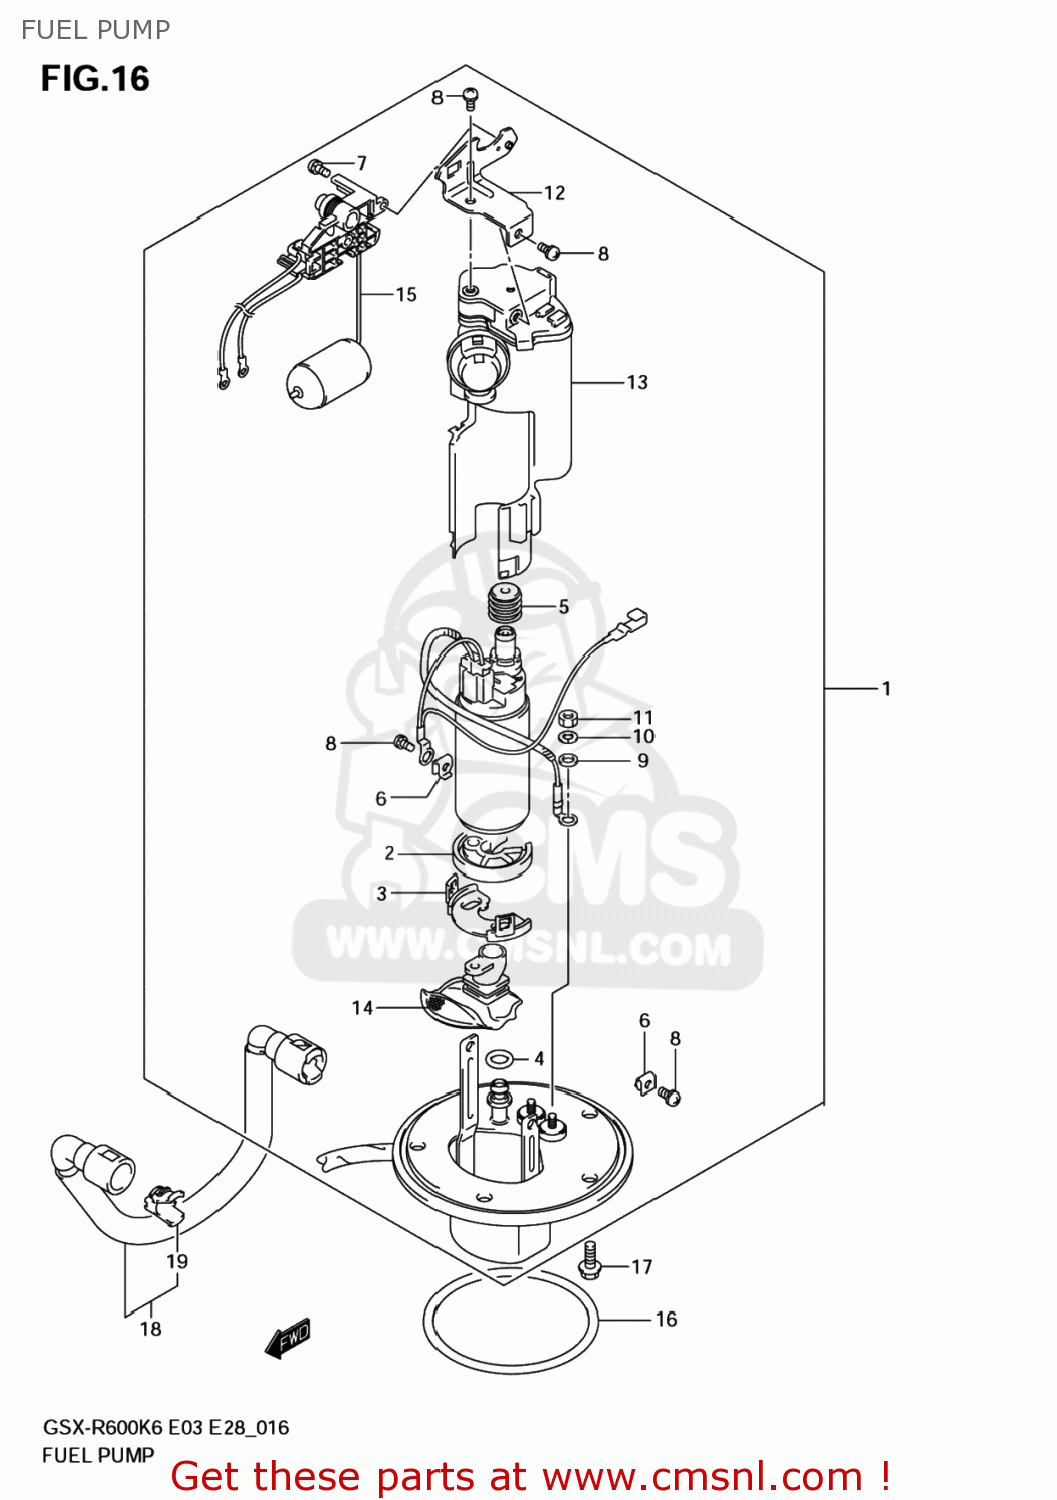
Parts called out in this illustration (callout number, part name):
1	PUMP ASSY,FUEL
2	CUSHION
3	HOLDER,FUEL PUMP
4	O RING
5	BUSH,FUEL PUMP
6	NUT
7	SCREW
8	SCREW
9	WASHER
10	WASHER,SPRING
11	NUT
12	BRACKET,FUEL GAUGE
13	FILTER,FUEL
14	STRAINER,FUEL
15	GAUGE ASSY,FUEL LEVEL SENSOR
16	O RING,FUEL PUMP
17	BOLT
18	HOSE,FUEL
19	RETAINER
